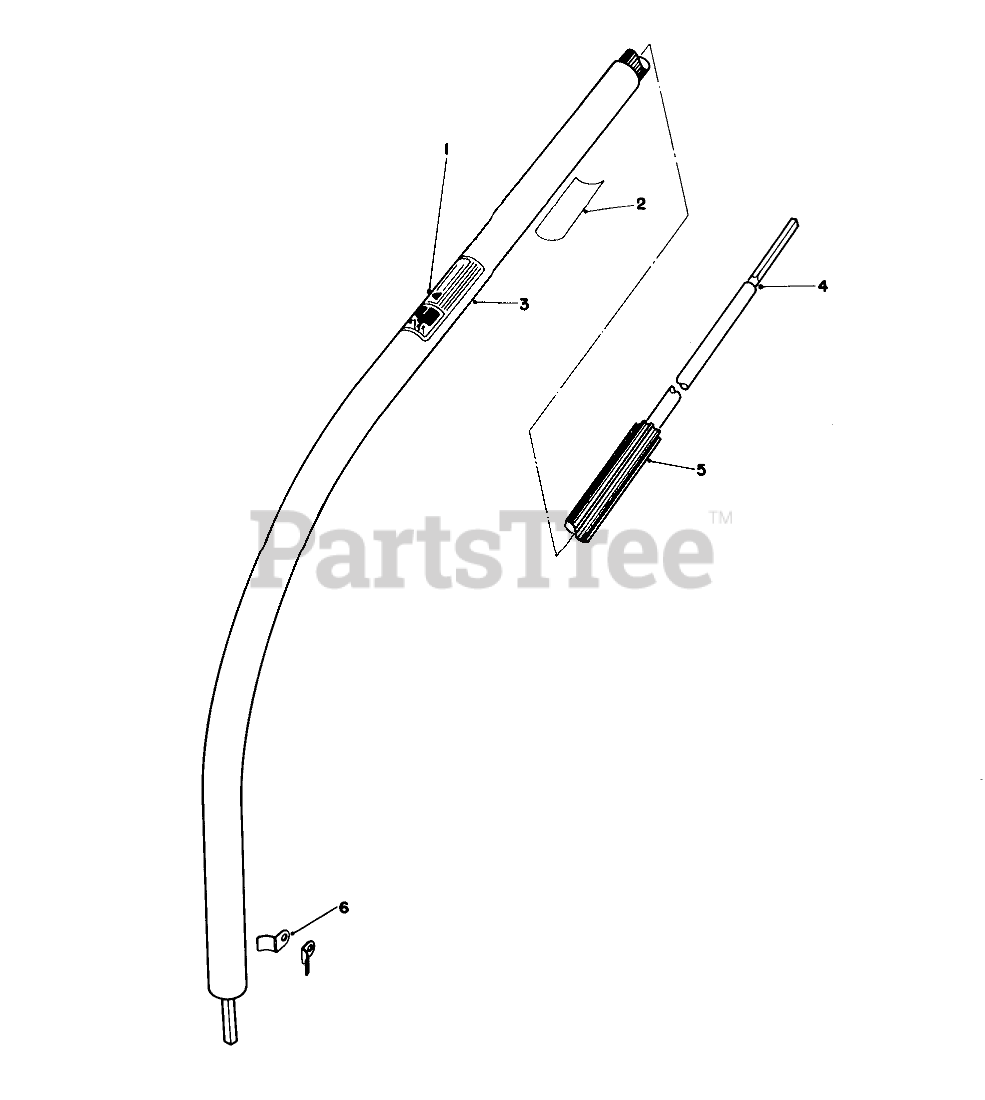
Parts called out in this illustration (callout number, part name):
1	Decal Warning
2	REP. SERIAL PLT
3	Tube-Lower Shaft Housing Assembly (Incl. Ref. #1)
4	Shaft-Flex Assembly (Incl. Ref. #5)
5	Casing-Flex Shaft
6	LOWER TUBE RETAINER
